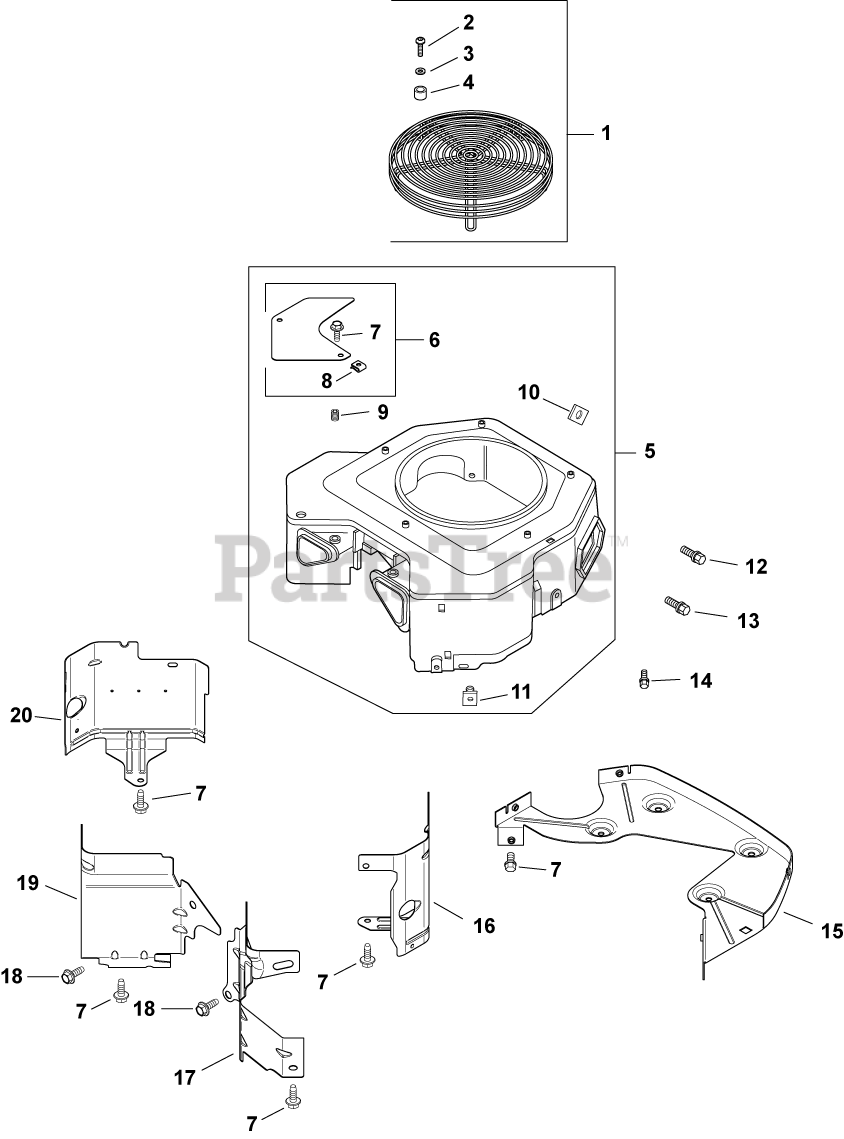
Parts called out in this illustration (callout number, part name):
1	KIT, GUARD
2	SCREW, PAN HEAD-USE 25 086 160-S
3	WASHER, FLAT 7/32"
4	SPACER USE 25 112 30-S
5	KIT, BLOWER HOUSING
6	KIT, ACCESS PANEL USE 25 755 20-S
7	SCREW,FLG THD FRM M6X1.0X16-(#25086397S)
8	CLIP, MOUNTING-USE 25 154 13-S
9	SCREW, SKT SET #10-24X1/4"
10	NUT, PLASTIC (KM)-USE 25 100 37-S
11	NUT, PLASTIC
12	SCREW - USE M-545016-S
13	SCREW, FLG THD FRM M5X.8X20-(#25086399S)
14	SCREW,FLG THD FRM M5X0.8X16-(#25086398S)
15	PLATE, BACKING (OIL COOLER)-USE 24 146 5
16	BAFFLE,VALLEY #2SIDE(KM)-USE 24 063 88-S
17	BAFFLE, VALLEY #2 SIDE-USE 24 063 94-S
18	SCREW, FLG THD FRM M5X.8X10
19	BAFFLE, VALLEY (CV)-USE 24 063 93-S
20	BAFFLE, RIGHT BARREL-USE 24 063 85-S
